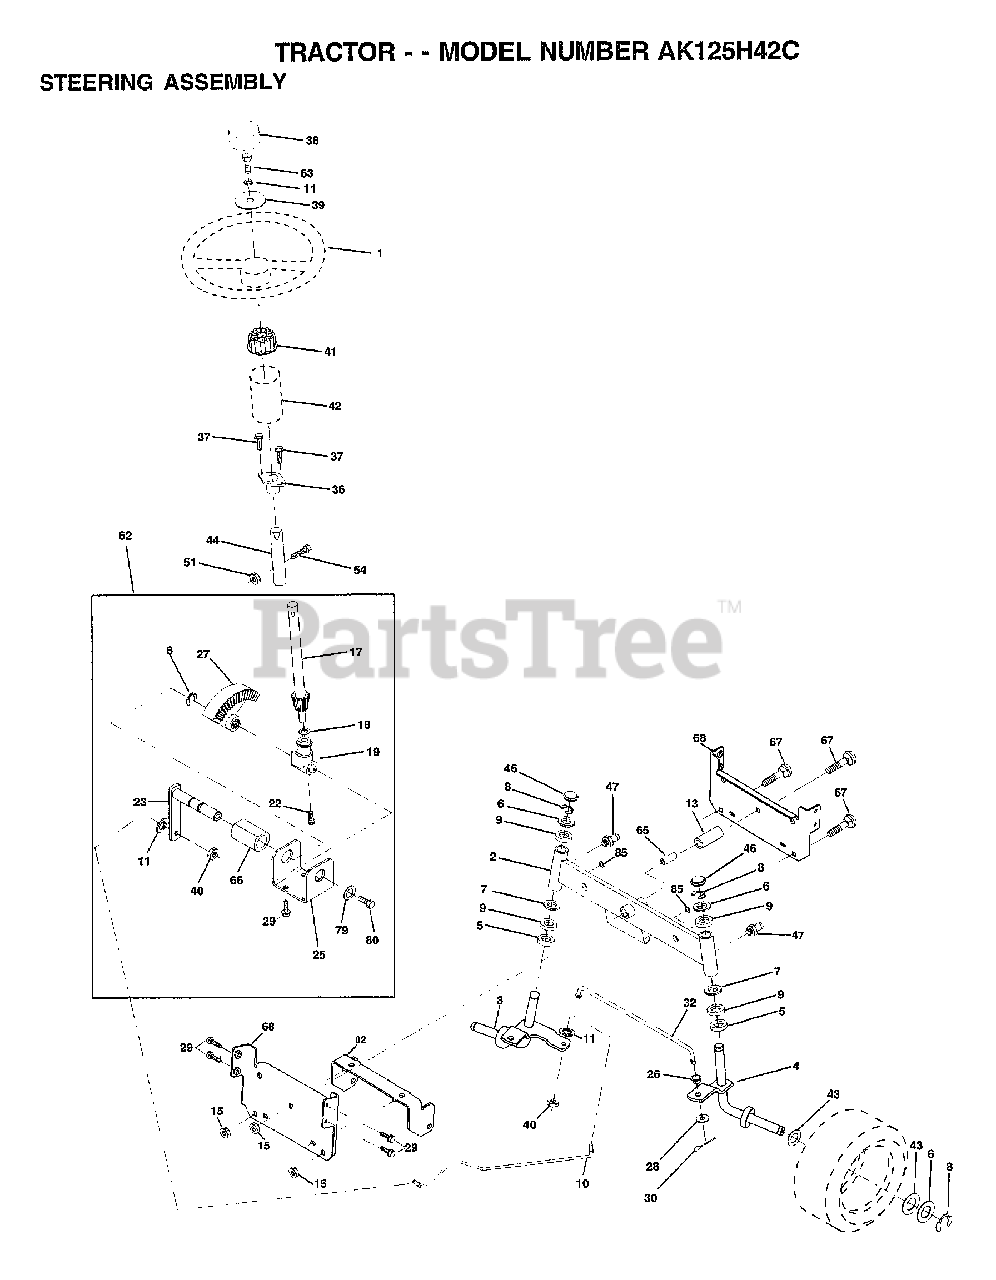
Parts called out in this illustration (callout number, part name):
2	AXLE ASSEMBLY
3	SPINDLE ASM
4	SPINDLE ASM
5	WASHER .T
6	WASHER
7	WASHER
8	RING
9	COL. SRTG. BEAR.
10	LINK DRAG
11	LOCKWASHER
13	SPACER BEARING
15	NUT.HXFLG.LOCK.
17	SHAFT ASM STEERIN
18	THRUST WASHER
19	SUPPORT.SHAFT.STEER
22	SCREW.HX.WSH.HD
23	SHAFT.ASM.PITMAN
25	BRKT-STEERING
26	BUSHING.DRAGLINK
27	GEAR SECTOR
28	WASHER
29	SCREW
30	COTTER PIN
32	TIE ROD
36	BUSHING.STEERING
37	"SCREW-TT,10-32 FL"
38	ST WHL INSERT CAP
39	WASHER
40	GRIPCO NUT
41	ADAPTER LT
42	BOOT.STEERING.DASH.P/L
43	WASHER
44	EXT SHAFT STEERIN
46	CAP
47	ZERK M
51	NUT
54	BOLT
62	KIT.STEER.ASM
63	BOLT
65	"SPACER BRCAE,AXLE"
66	"BEARING-ARM,PITMA"
67	BOLT RDHD 3/8-16
68	BRACE AXLE
79	WASHER
80	BOLT.HX.NYLON3/8-16X3/
82	BRKT SUSP CHASSIS FRT
85	XMAS TREE FASTNER
